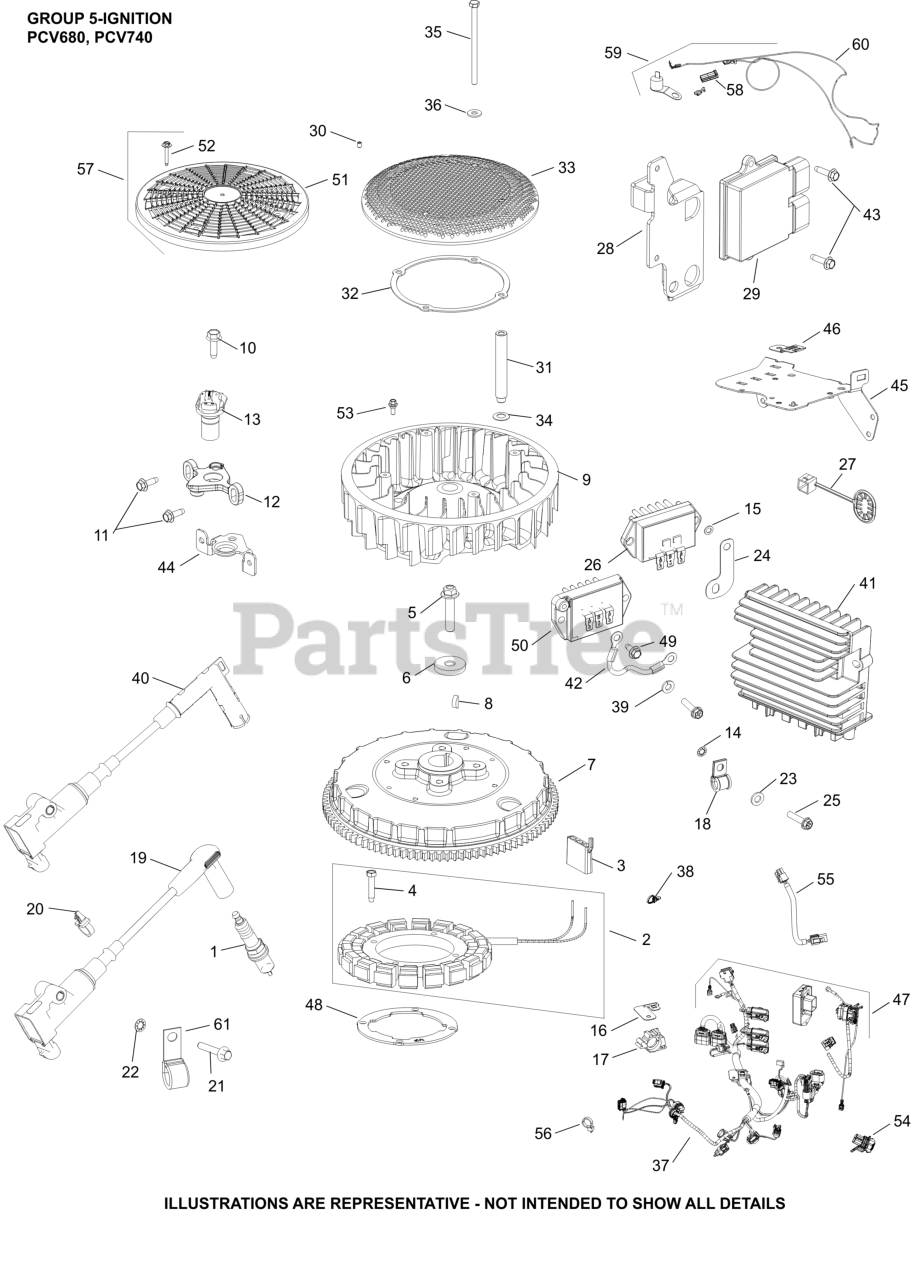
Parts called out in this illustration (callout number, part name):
1	SPARK PLUG, RFI
3	CONNECTOR
5	SCREW, FLG M10X1.5X45-USE 25 086 361-S
6	WASHER, FLAT 13/32"
7	FLYWHEEL, ASSEMBLY
8	KEY, 3/16" X 5/8"
11	SCREW, THREAD FORMING
13	SENSOR, SPEED
14	WASHER, INT TOOTH LOCK #10
21	SCREW, FLG (BLACK) M6X1.0X34
22	WASHER, INT TOOTH LOCK 1/4"
25	SCREW, HEX FLANGE HI-LO
27	CAP, CONNECTOR
28	BRACKET, ECU
37	HARNESS, WIRING ASSEMBLY
40	COIL, IGNITION - EFI (RFI/EMC)
44	BRACKET, SENSOR
49	SCREW, THREAD FORMING
50	REGULATOR, RECT (20-30AMP, FW W/OVP)
53	BOLT, SHOULDER
58	CONNECTOR (1 CONTACT)
59	KIT, HI TEMP CUTOUT SENSOR
61	CLIP, CABLE (KM)
NI	MODULE, ECU-USE 24 584 234-S
NI	SCREW, THREAD FORMING
NI	CLAMP, INSULATED
NI	KIT, 25 AMP STATOR ASSY.
